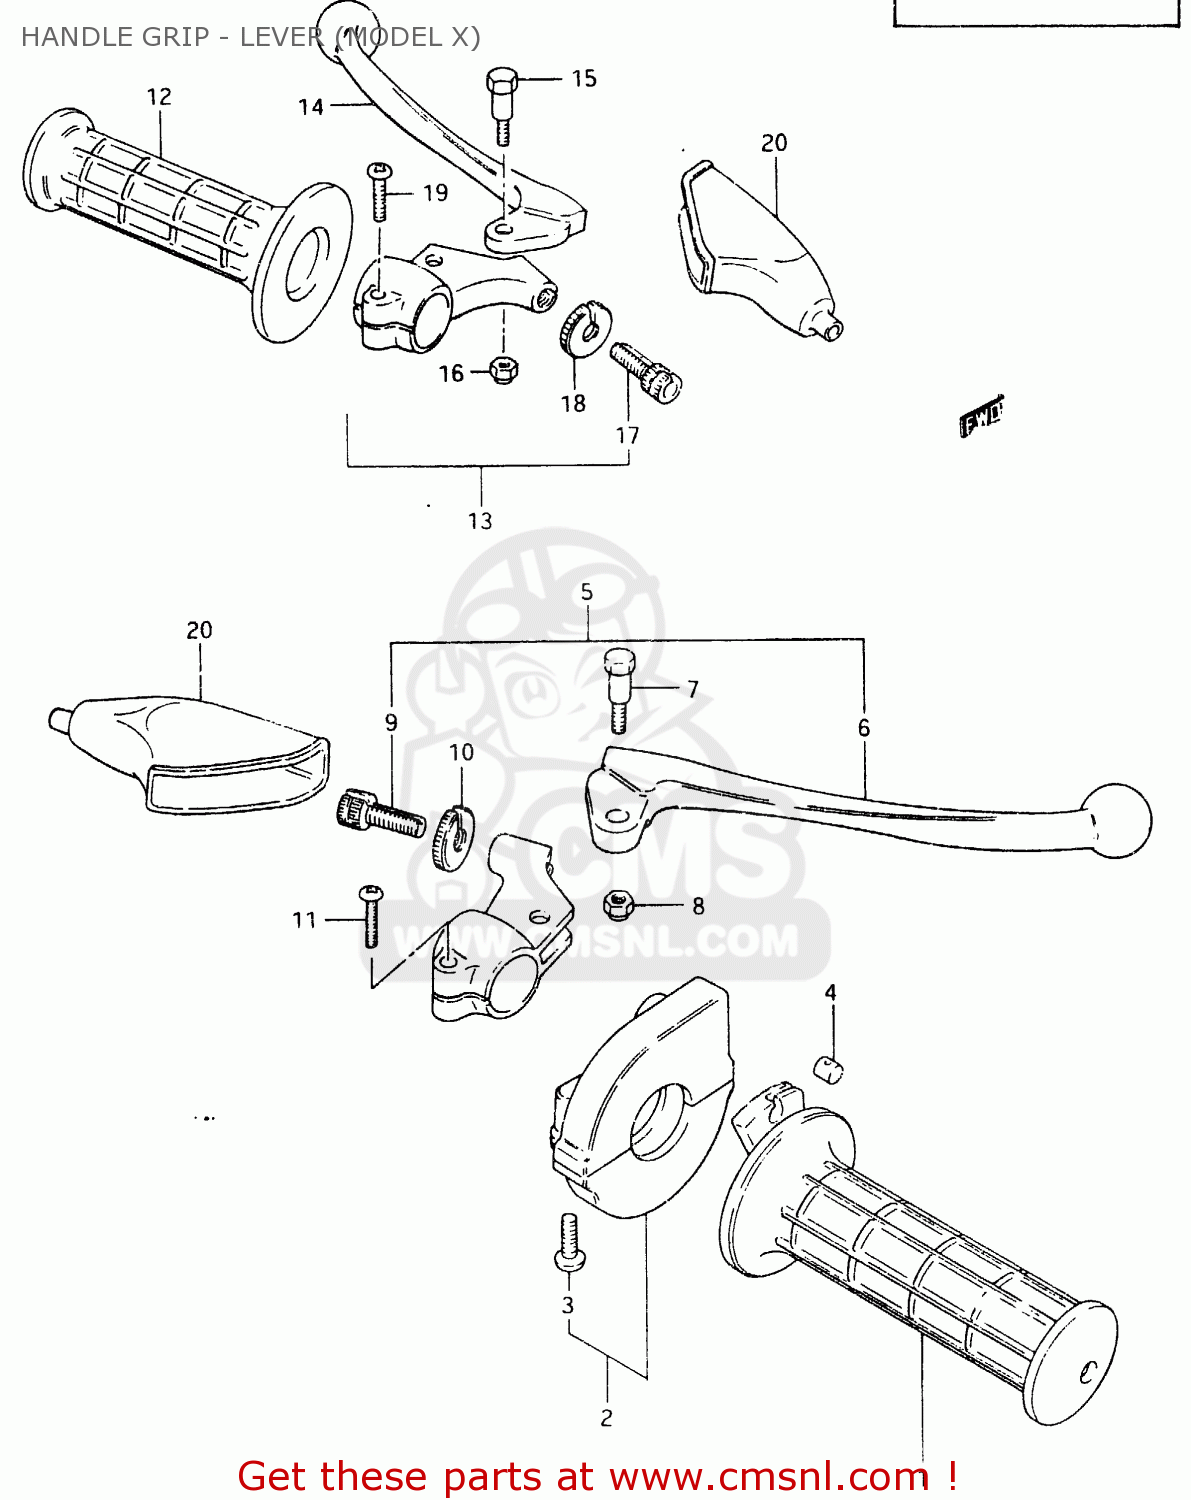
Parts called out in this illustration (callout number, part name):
1	GRIP,THROTTLE
2	CASE ASSEMBLY,THROTTLE
3	SCREW
4	PIECE,THROTTLE END
5	LEVER ASSEMBLY,BRAKE
6	LEVER,BRAKE
7	BOLT,LEVER
8	NUT 6MM
9	ADJUSTER,CABLE
10	NUT,CABLE ADJUSTER
11	SCREW
12	GRIP,LEFT
13	LEVER ASSEMBLY,CLUTCH
14	LEVER,CLUTCH
15	BOLT,LEVER
16	NUT 6MM
17	ADJUSTER,CABLE
18	NUT,CABLE ADJUSTER
19	SCREW
20	COVER,CLUTCH LEVER
